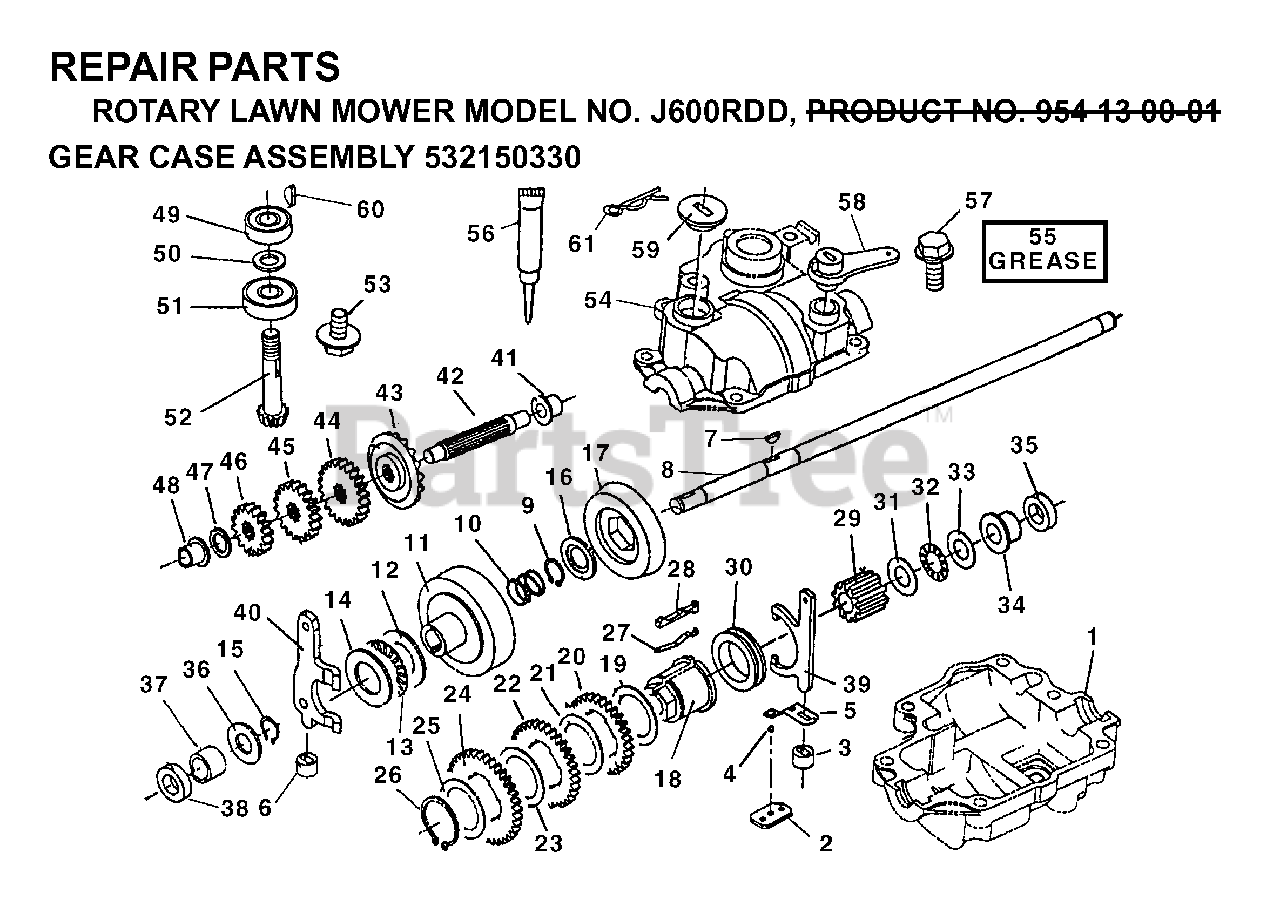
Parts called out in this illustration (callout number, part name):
3	SUPPORT FORK, SHIFT
17	CONE
18	SHIFT COLLAR
36	WASHER
58	SHIFTER ARM
